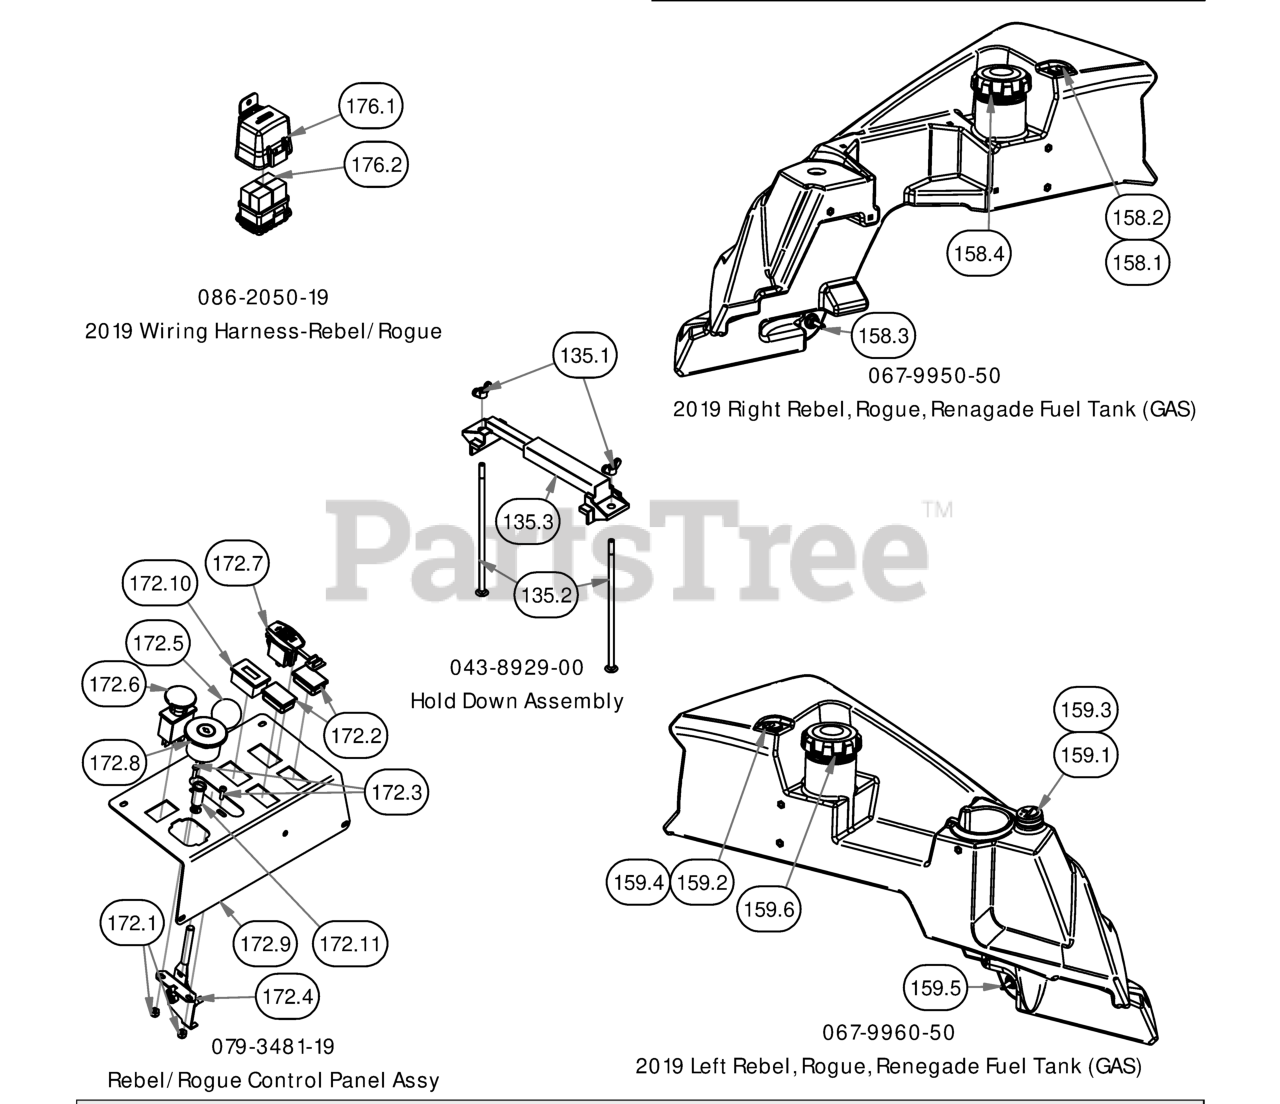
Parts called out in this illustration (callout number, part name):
135.1	1/4" Wing Nut
135.2	1/4-20 X 8 Carriage Bolt
135.3	Battery Hold Down
158.1	Roll Over Valve Grommet
158.2	Rollover Valve
158.3	Fuel Pick-up
159.1	Fuel Gauge with Grommet
159.2	Roll Over Valve Grommet
159.3	Fuel Gauge Grommet
159.4	Rollover Valve
159.5	Fuel Pick-up
172.1	10-24 Nylon Insert Locknut Zinc Orange Nylon
172.2	Light Plug
172.3	10-24 X 5/8 BS Button Head Bolt
172.4	Universal Throttle
172.5	Throttle Knob
172.6	PTO Switch
172.8	Ignition Switch
172.9	2019 Outlaw Control Panel
172.10	Tachometer
176.1	Relay Block Cover Replacement Kit
